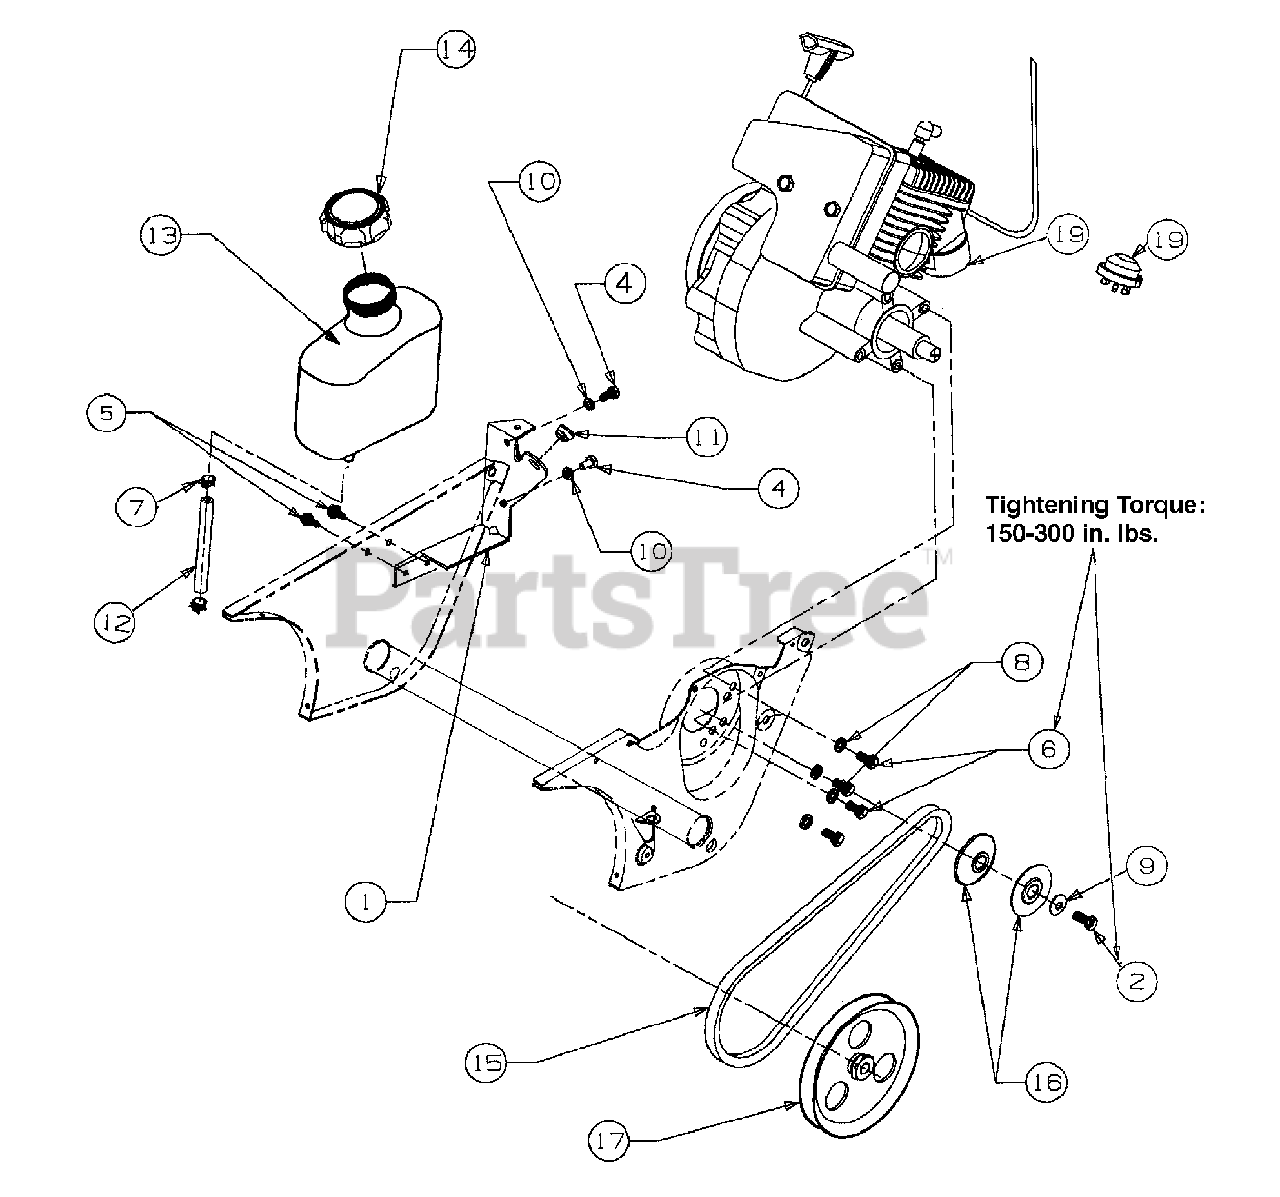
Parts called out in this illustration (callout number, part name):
1	Support Bracket, Gas Tank
2	Hex Cap Screw
4	Hex Screw
5	Washer Screw
6	Hex Cap Screw
7	Hose Clamp
8	Lock Washer
9	Bell Washer
10	Lock Washer
11	Plastic Bushing
12	Hose, Fuel Line-16"
13	Fuel Tank-2 qt.
14	Fuel Cap
15	V-Belt
16	V-Pulley Half
17	Pulley
19	Obtain from engine manufacturer
